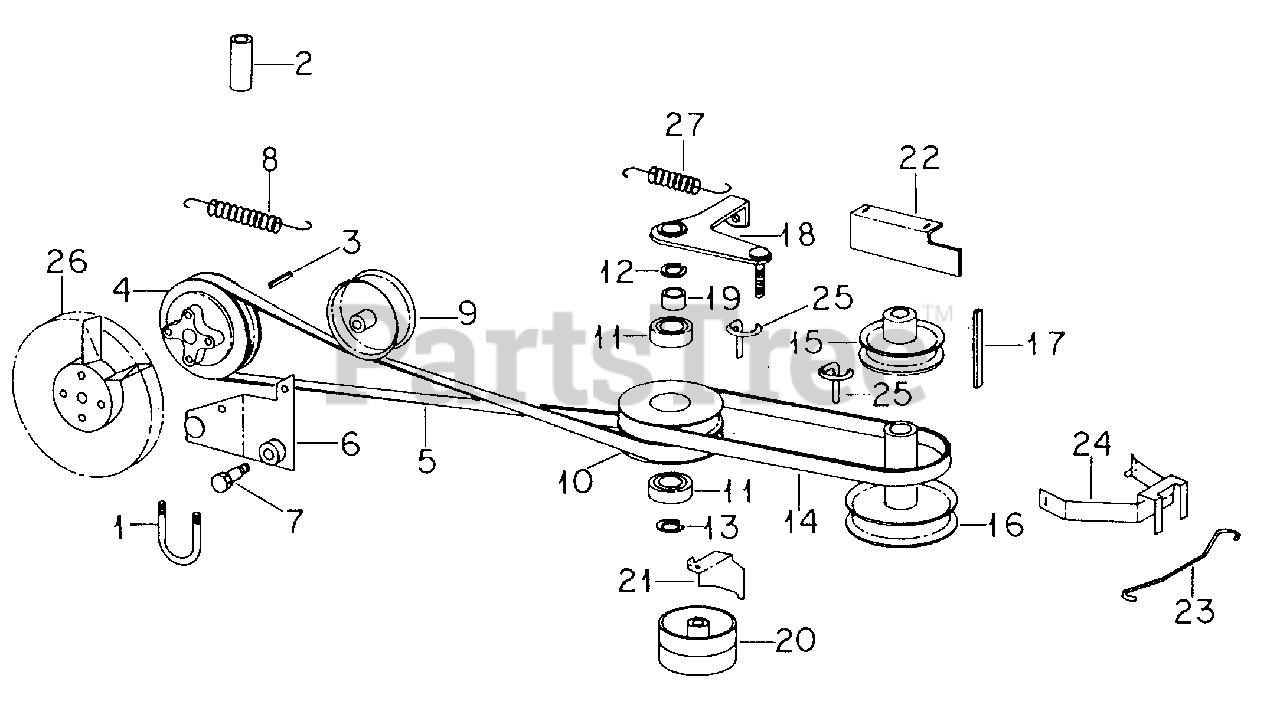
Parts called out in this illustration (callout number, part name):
2	Spacer, Transaxle Mounting
3	Key, 1/8 X 1/2 Woodruff 3
4	Pulley, Transmission Drive
5	Belt, Hydrostatic Final Drive
6	Arm Assy, Belt Tensioning
7	Bolt, IPTO Shoulder
8	Spring, Extension
9	Pulley, Final Drive Idler
10	Pulley, Intermediate Drive
11	Bearing, Intermediate Pulley
12	Ring, External Retaining
13	Ring, Internal Retaining
14	Belt, Hydrostatic Clutching
15	Pulley, Hydrostatic Engine Drive
16	Pulley, Mower Drive, 4-5/8 Inch diameter
17	Key, 1/4 X 2-3/4 Sq Parallel
18	Bushing Assy, Clutch
19	Bushing
20	Pulley, Mower Shifter Idler
21	Guide, Belt
22	Guide, Belt
23	Support, Belt Guide
24	Guide, Engine Belt
25	Guide, Transaxle Belt
26	Fan, Hydrostatic 6 Blade
27	Spring, Extension
